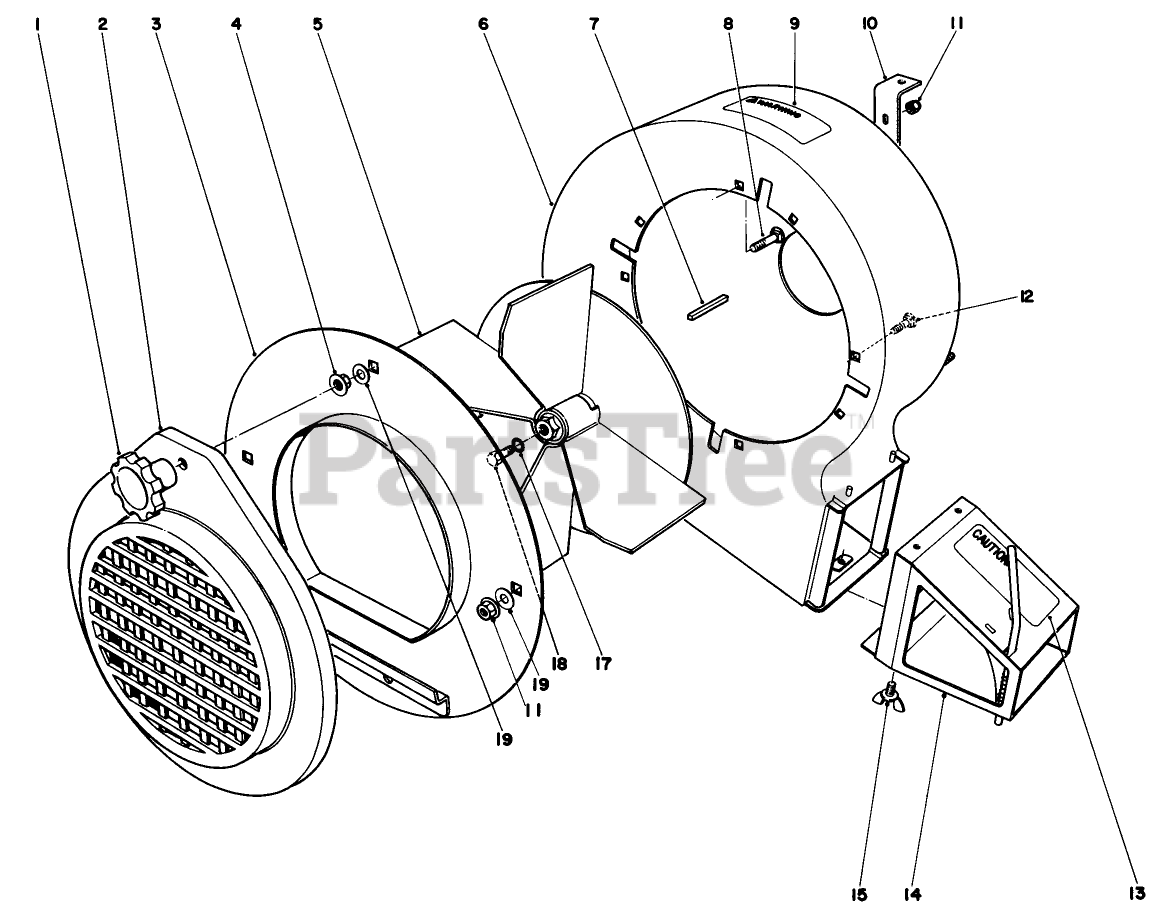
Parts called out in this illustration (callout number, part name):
2	INTAKE-BLOWER
3	Blower Cover
4	NUT-HF
5	Fan
6	Blower Housing
7	KEY-SQUARE
8	SCREW-CARR
9	WARNING DECAL
10	Bracket-Housing
11	NUT-LOCK, CONE
12	SCREW-CARR
13	EXHAUST DECAL
14	Blower, Exhaust (Incl.Ref. #13)
15	1/4 - 20 3/4 WING SCR
17	WASHER-LOCK
18	Capscrew
19	WASHER-FLAT
